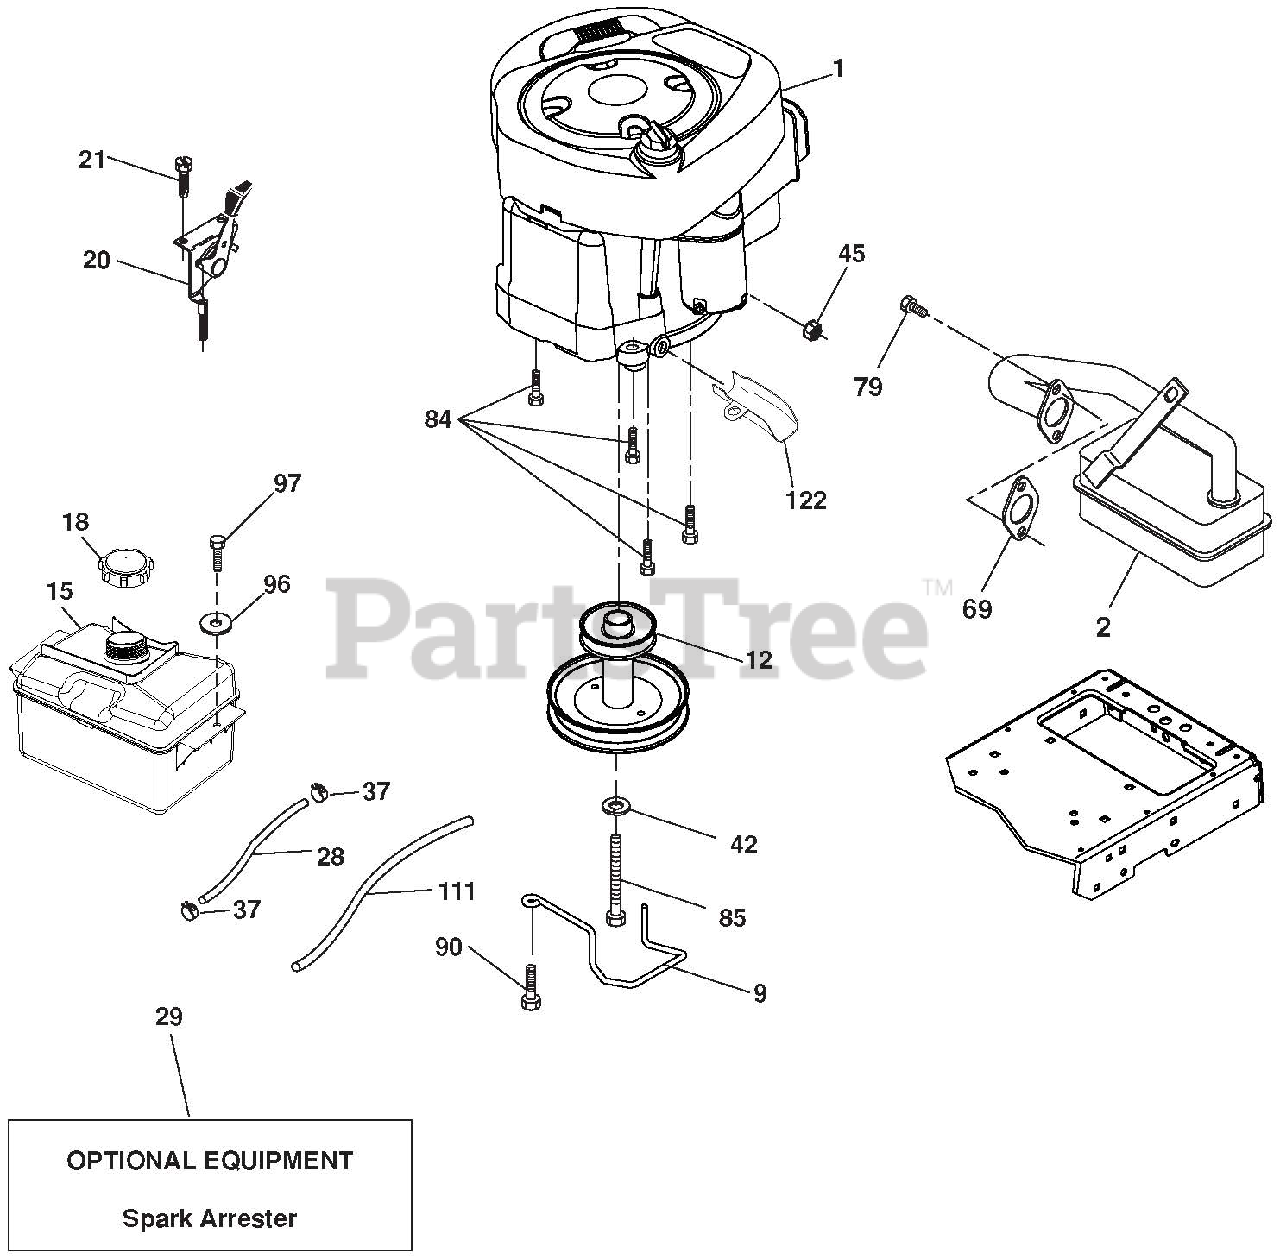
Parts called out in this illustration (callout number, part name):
2	Muffler Exhaust B&S
9	KEEPER.BELT.ENGINE.3.25"NSTL
12	ENGINE PULLEY
15	TANK FUEL
18	CAP.FUEL
20	CONTROL.THROTTLE
28	LINE.FUEL.1/4" ID(LOW PREM)
29	KIT.SPARK ARRESTOR(392390 B&S)
37	CLAMP.HOSE.BLK.
42	WASHER.LOCK.HVY HLCL.SPR.7/16
45	Nut, Keps Hex 1/4-20 unc
69	Gasket Eng 1 313 Id Tin Plated
79	SCREW.SOCKET HD.5/16-18 X .75
84	Screw 3/8-16 x 1-1/4
85	BOLT.HEX.7/16-20X4XGR5-1.5THR.
90	SCREW.3/8-16X1.SMGML.TAP/R.BLK
96	WASHER.9/32 X 7/8 X 16GA.
97	SCREW.HEXWSH.THDROL.1/4-20X3/4
111	PURGE.LINE.CARB
122	Extension Drain Oil
